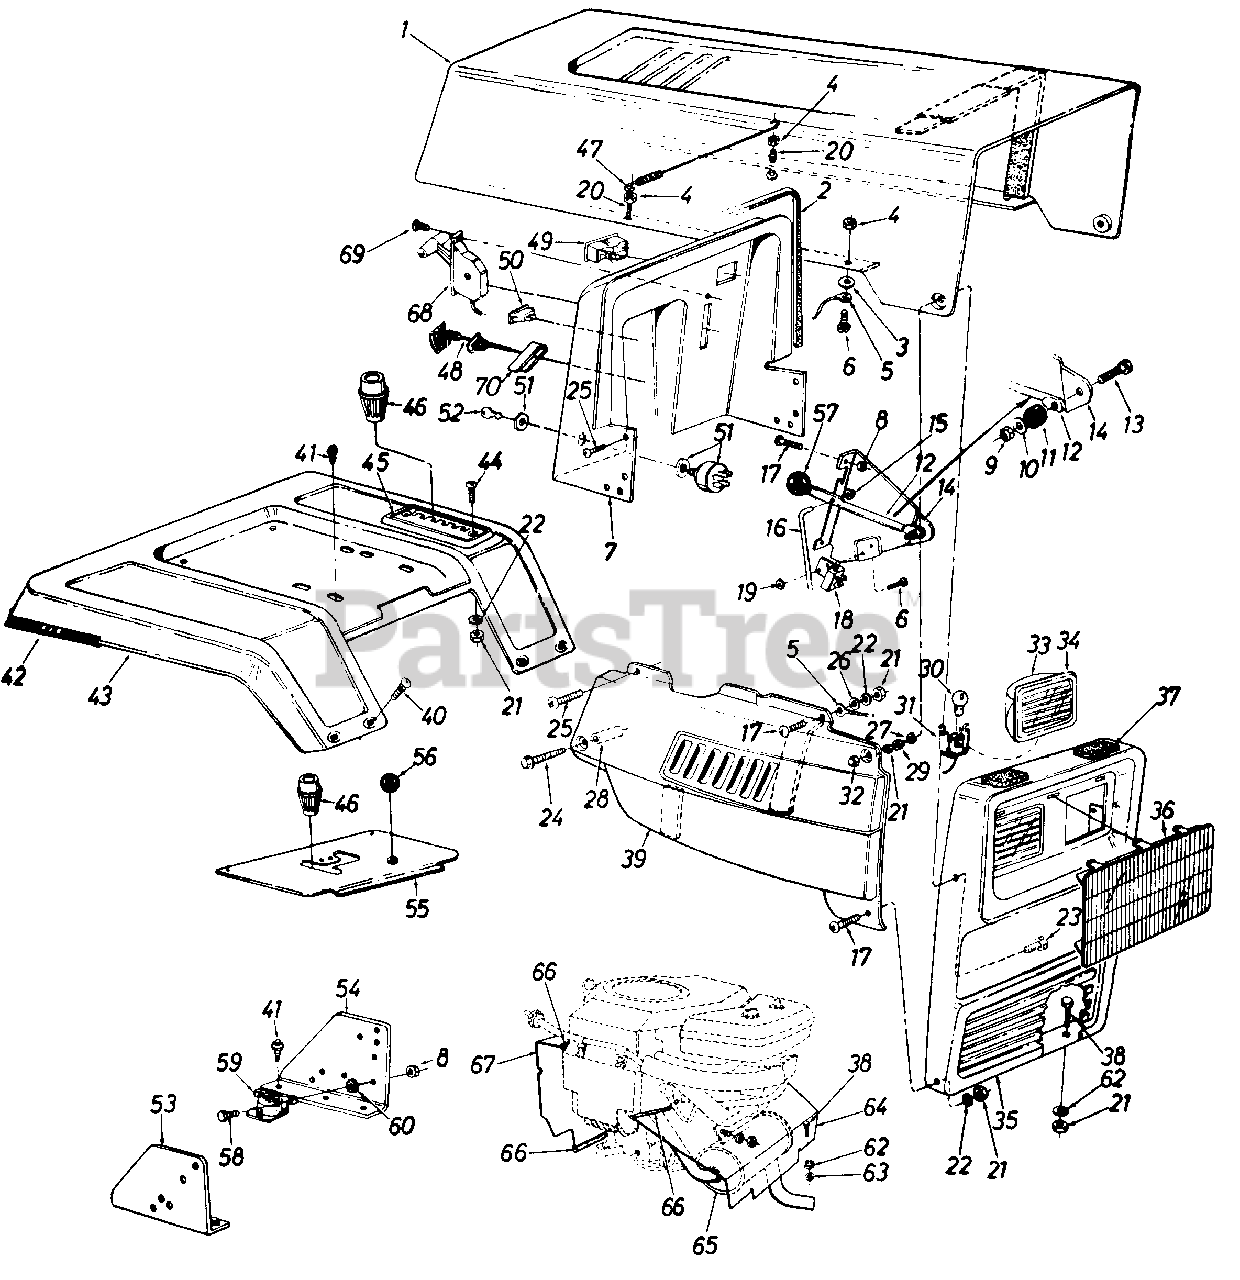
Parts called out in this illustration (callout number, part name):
3	Fl-Wash. .20" I.D. x .41" O.D.
4	Hex Sems Nut #10-.24 Thd.
5	Hood Stop
6	Truss Mach. Scr. #10-24 x .5" Lg.
9	Hex L-Nut 1/4-2O Thd.
10	Fl-Wash. .281" I.D. x .73" O.D.
11	Rubber Washer
12	PTO Lever
13	Hex Bolt 1/4-20 x 1.25" Lg.
14	Deck Clutch Control Brkt.
15	Push Cap
16	Deck Control Rod
17	Truss Mach. Scr. 1/4-20 x .5" Lg.
18	Safety Switch
19	Hex Nut #10-24 Thd.
20	Hex Bolt 10-24 x 1.0" Lg.
21	Hex Nut 1/4-2O Thd.
22	L-Wash. 1/4" I.D.
23	Hex Bolt 1/4-2O x .88" Lg.
24	Hex Wash. TT-Tap Scr. 1/4-20 x 1.75" Lg.
25	Hex TT-Tap Scr. 1/4-20 x .75" Lg.
26	Fl-Wash. .25" I.D. x .62"
27	Spr. Wash. .39" I.D. x .62"
28	Spacer .26" I.D. x .375"
29	Shld. Spacer .375" Dia. x .125" Lg.
30	Lamp
31	Socket
32	Acorn Nut 1/4-20 Thd.
33	Headlight Housing
34	Headlight Lens
37	Foam Strip
38	Hex Bolt 5/16-18 x .75" Lg.
41	Hex Wash. AB-Tap Scr. 5/16 x .75" Lg.
42	Trim Strip-81" Lg.
43	Fender
44	Truss Mach. Scr. 1/4-20 x .62" Lg.
45	7-Speed Selector Plate
46	Shift Knob
47	Hood Spring
48	Choke Control 46" Lg.
49	Ammeter
50	Light Switch
51	Ignition Switch
52	Ignition Key
53	Dash Support Brkt.-R.H.
54	Dash Support Brkt.-L.H.
55	Transmission Cover
56	Ball Knob
57	Knob-Blade Clutch
58	Hex Bolt 1/4-20 x .5" Lg.
59	Solenoid
60	Ext. L-Wash. 1/4" I.D.
62	L-Wash. 5/16" I.D.
63	Hex Nut 5/16-18 Thd.
64	Front Heat Shield
65	Muffler
66	Trim Strip 12" Lg.
67	Rear Baffle
68	Throttle Control Box Ass'y.
69	Truss Mach. AB-Tap Scr. #10 x .5" Lg.
70	Retainer Clip
